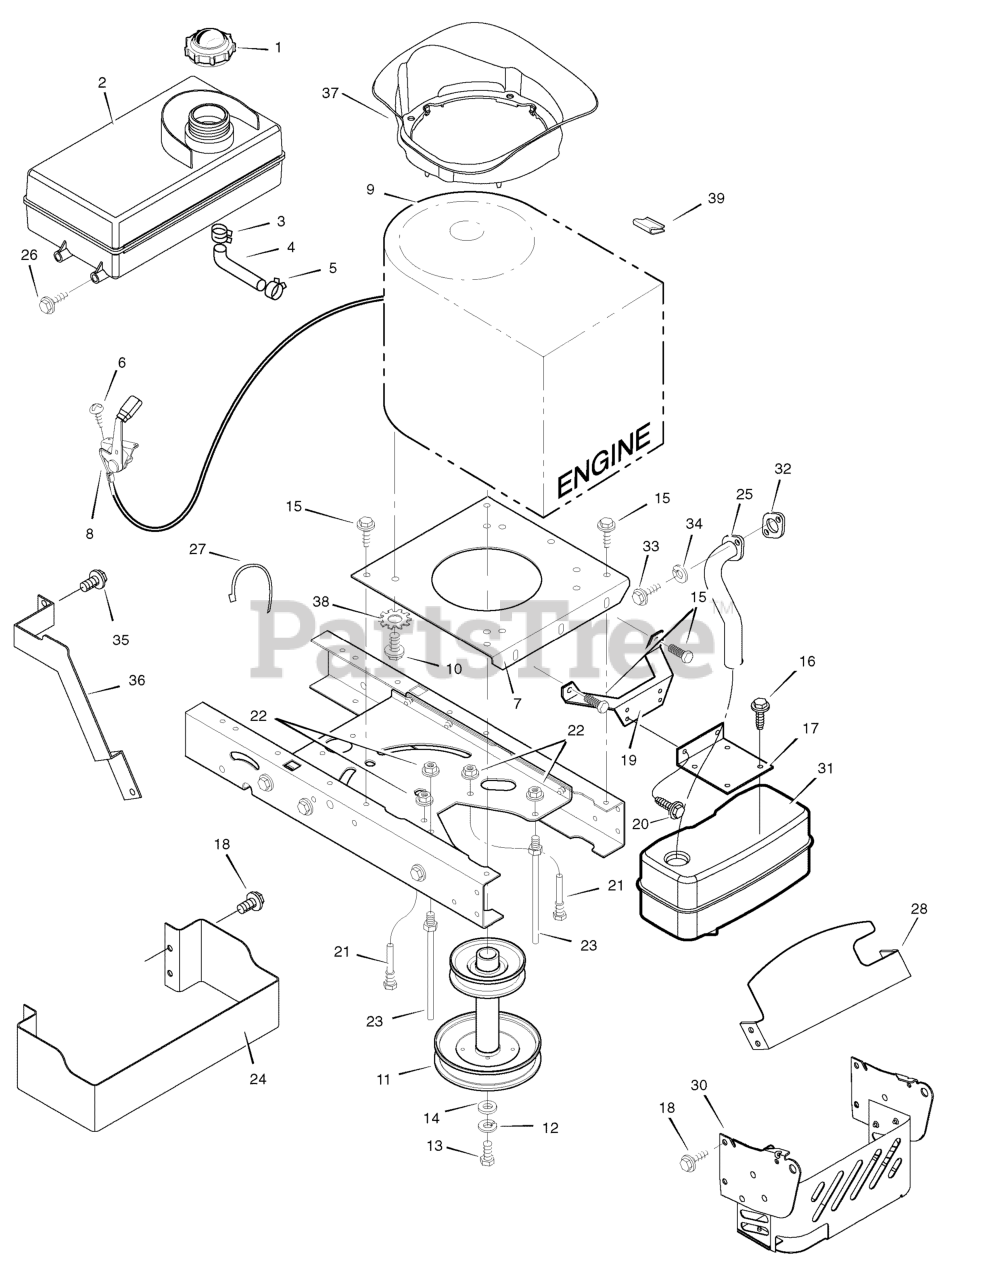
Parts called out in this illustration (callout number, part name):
1	Fuel Cap
2	TANK, Fuel 1.4 Gal.
3	Hose Clamp
4	Fuel Line (Must cut to length)
5	Hose Clamp
7	PLATE, Engine
8	THROTTLE CONTROL
9	Engine, Briggs & Stratton *
10	BOLT, Engine Mount
11	STACK PULLEY ASSEMBLY
12	LOCKWASHER
13	BOLT, Hex
17	BRACKET, Muffler
19	BRACKET, Muffler Mount
21	GUIDE, Belt
22	NUT, Flange
23	GUIDE, Belt
24	GUARD, Heat Shield
25	EXHAUST TUBE, Single
27	TIE, Strap, 5.38 Long
28	GUARD, Heat Shield, Upper
30	SHIELD, Heat
31	MUFFLER
32	GASKET, Exhaust
34	WASHER
35	BOLT, Washer Hex Head
36	GUARD, Exhaust Pipe
37	PLENUM, X1 M28/31
38	WASHER, Star .38 0.68X
39	CLIP, Wire Adhesive
